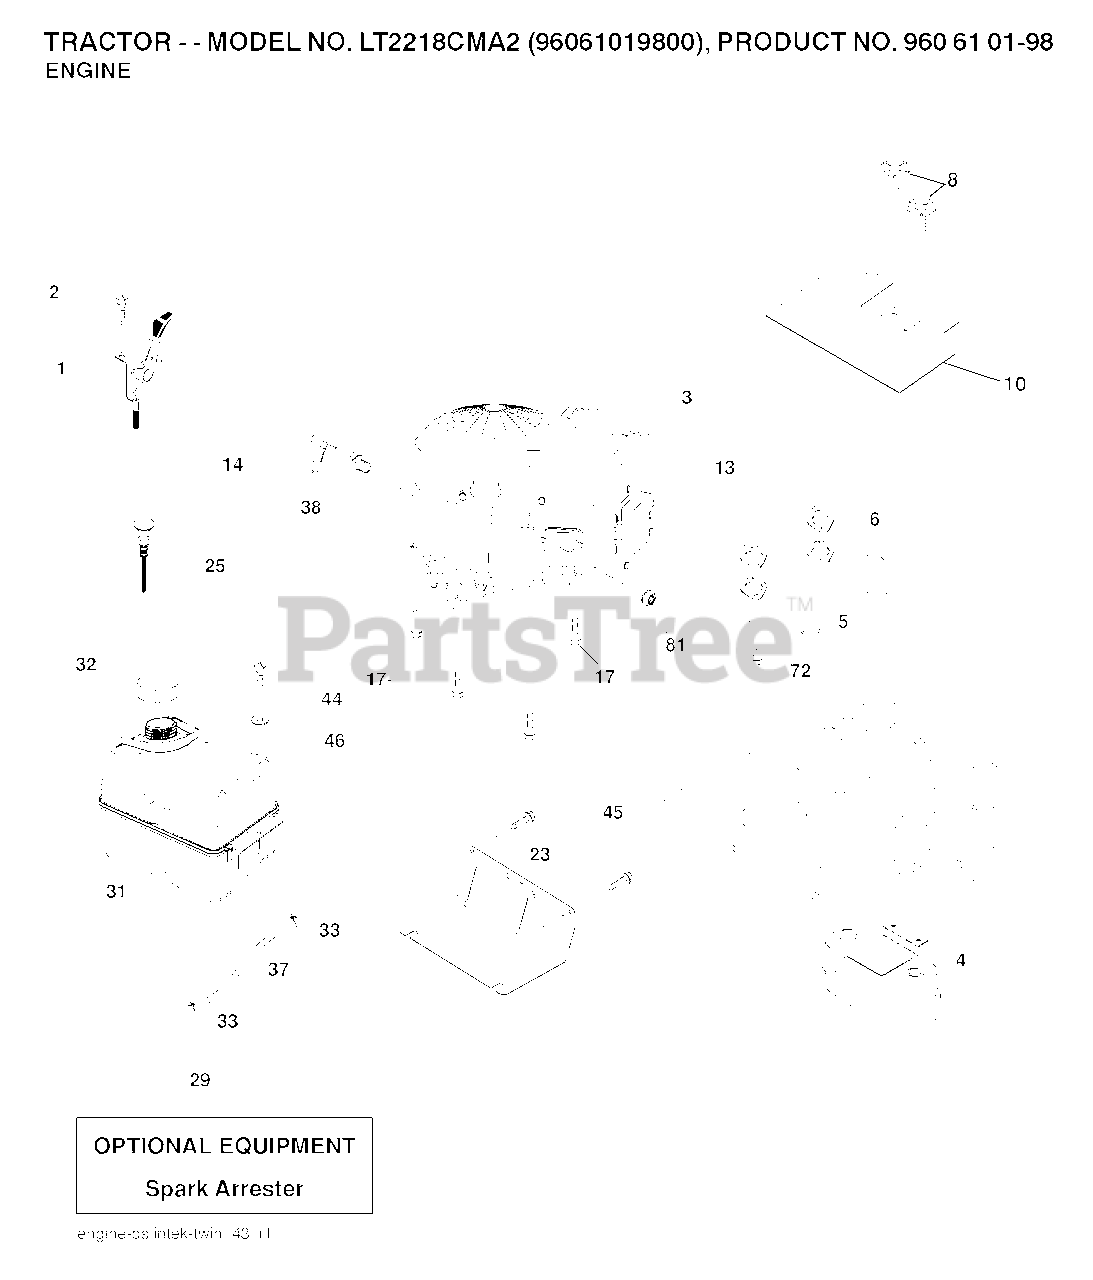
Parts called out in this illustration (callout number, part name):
1	THROTTLE CABLE
2	SCREW
4	MUFFLER.TWIN.CYL.LOW.TONE
5	EXHAUST TUBE RH
6	TUBE MANIFOLD LH
8	BOLT, 5/16-18 X 1 3/4
10	RP SHIELD HEAT MUFFLER
13	GASKET.MUFFLER
14	TUBE, DRAIN OIL ASM.
17	SCREW.3/8-16
23	SHEILD.BROWNING.DBR.GUARD
25	CONTROL CHOKE
29	ARRESTER SPARK (OPTIONAL)
31	FUEL TANK FRT 2 GAL.
32	FUEL CAP
33	HOSE CLAMP
37	LINE.FUEL.20
38	PLUG DRAIN OIL EASY
44	SCREW HEXWSHR 1/4-20X3/4
45	SCREW, 3/8-16X3/4
72	SCREW.SOCKET.HEAD.5/16-18
81	NUT
